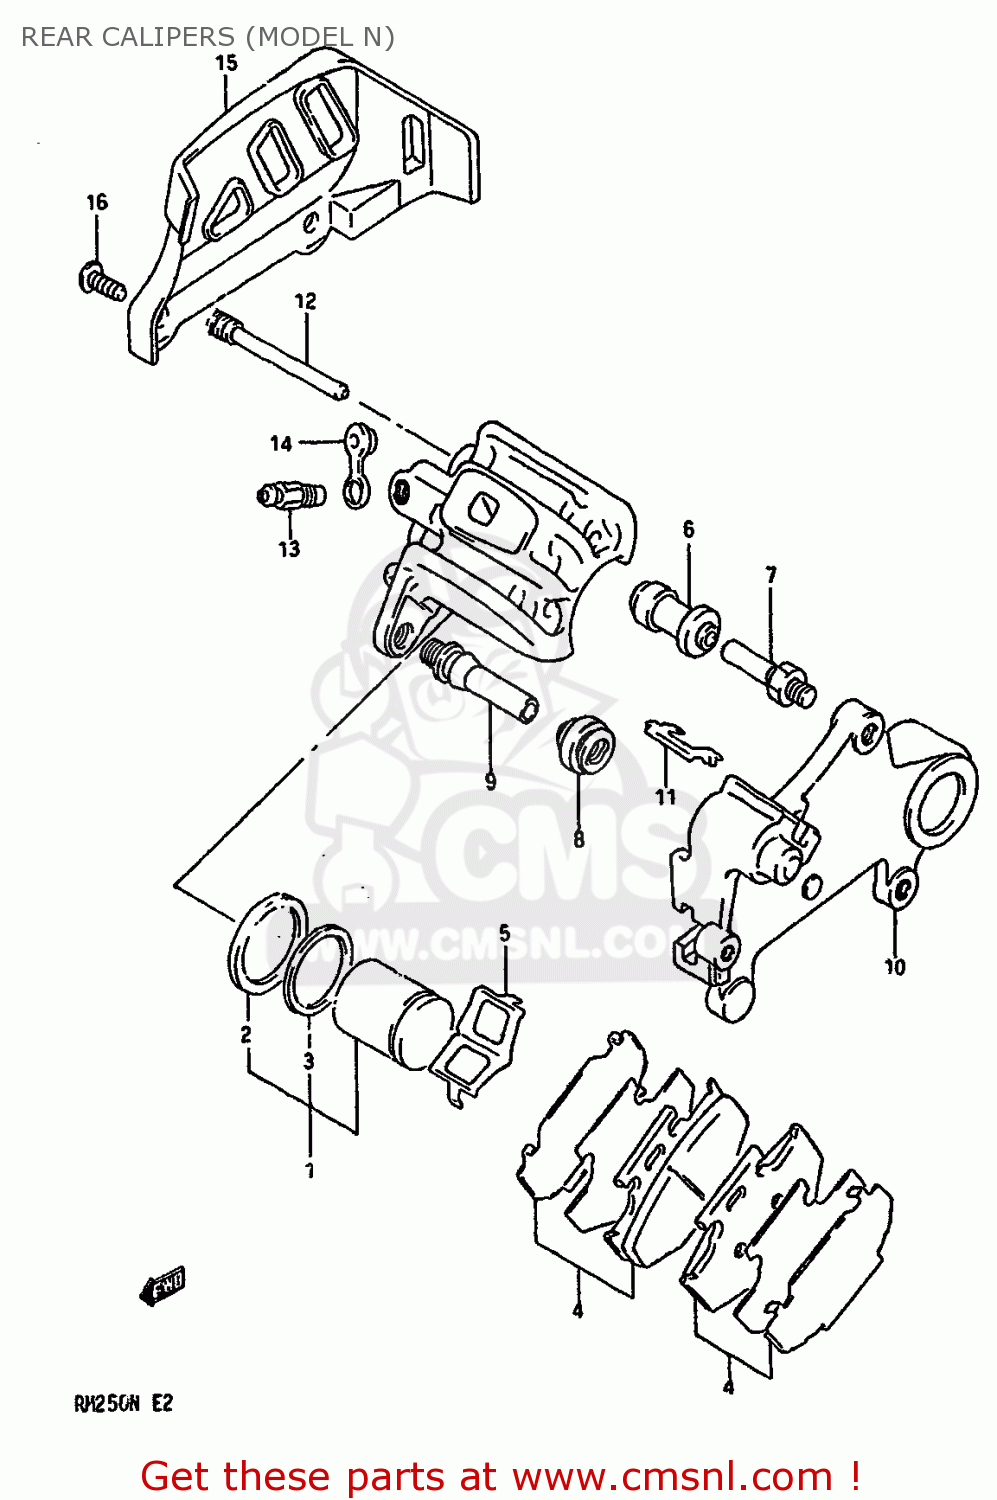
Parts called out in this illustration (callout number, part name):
1	PISTON SET
2	SEAL,PISTON
3	SEAL,DUST
4	PAD & SHIM SET (NAS)
5	SPRING,PAD
6	BOOT
7	PIN,BOLT
8	BOOT
9	PIN
10	BRACKET
11	RETAINER,BRACKET
12	PIN,HANGER
13	BLEEDER
14	CAP,BLEEDER
15	GUARD,RR CALIPER
16	SCREW(6X12)
